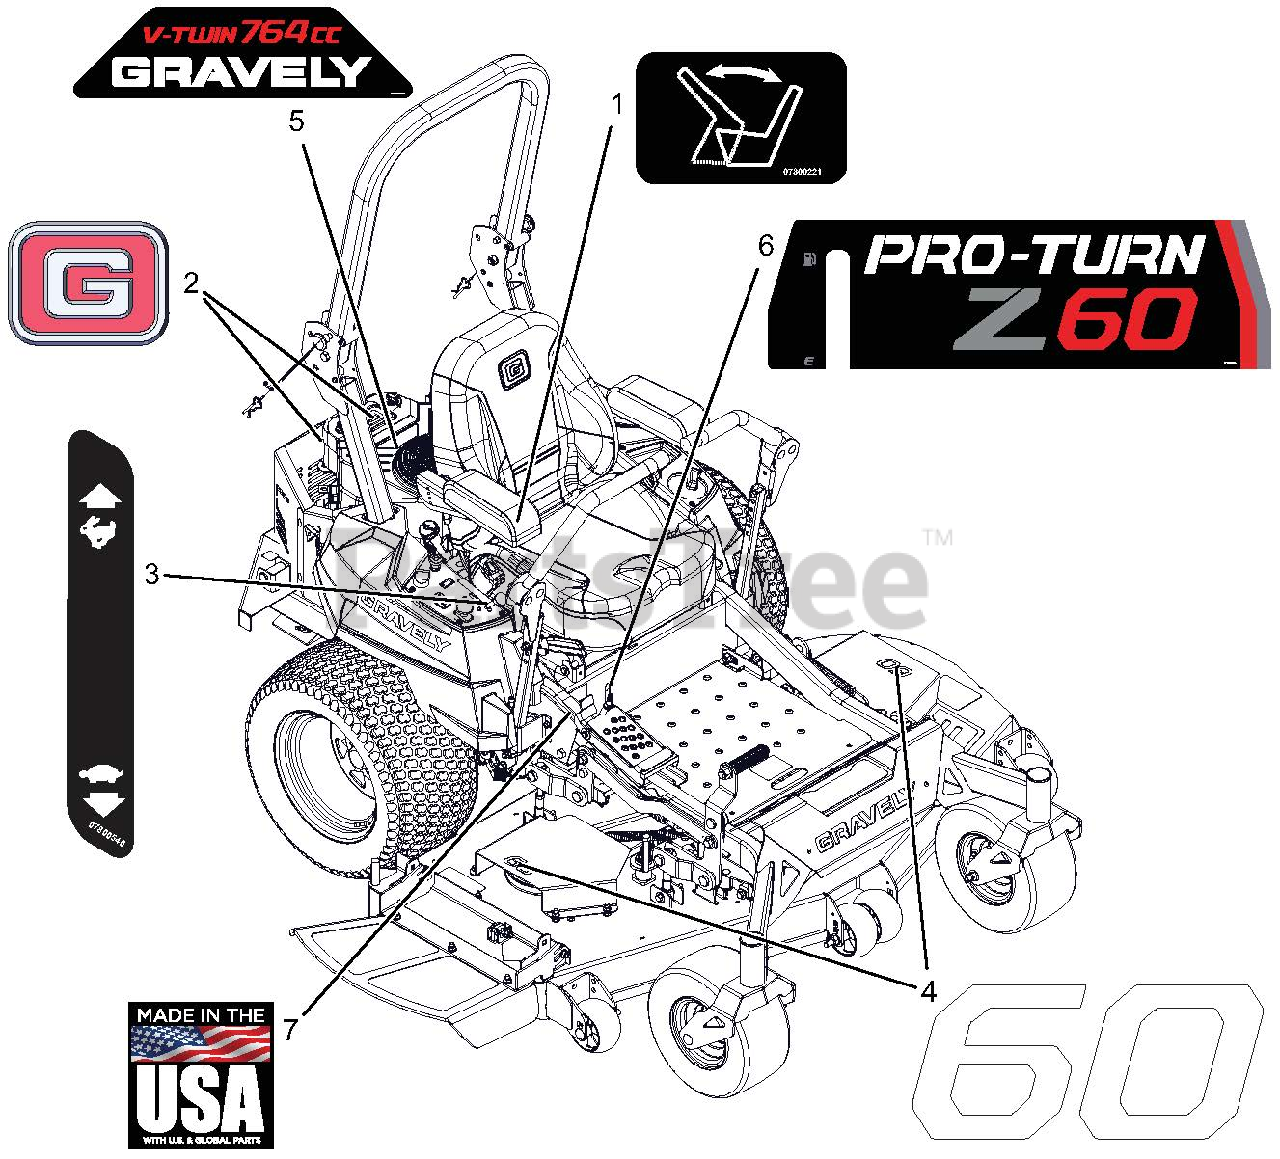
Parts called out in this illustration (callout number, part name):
1	DECAL - SEAT RELEASE
2	DECAL, GRAVELY BRAND
3	DECAL, DASH DECAL
4	DECAL, 60"
5	DECAL,ENGINE - GRAVELY 764CC
6	DECAL, PRO-TURN Z60
7	DECAL, MADE IN USA
